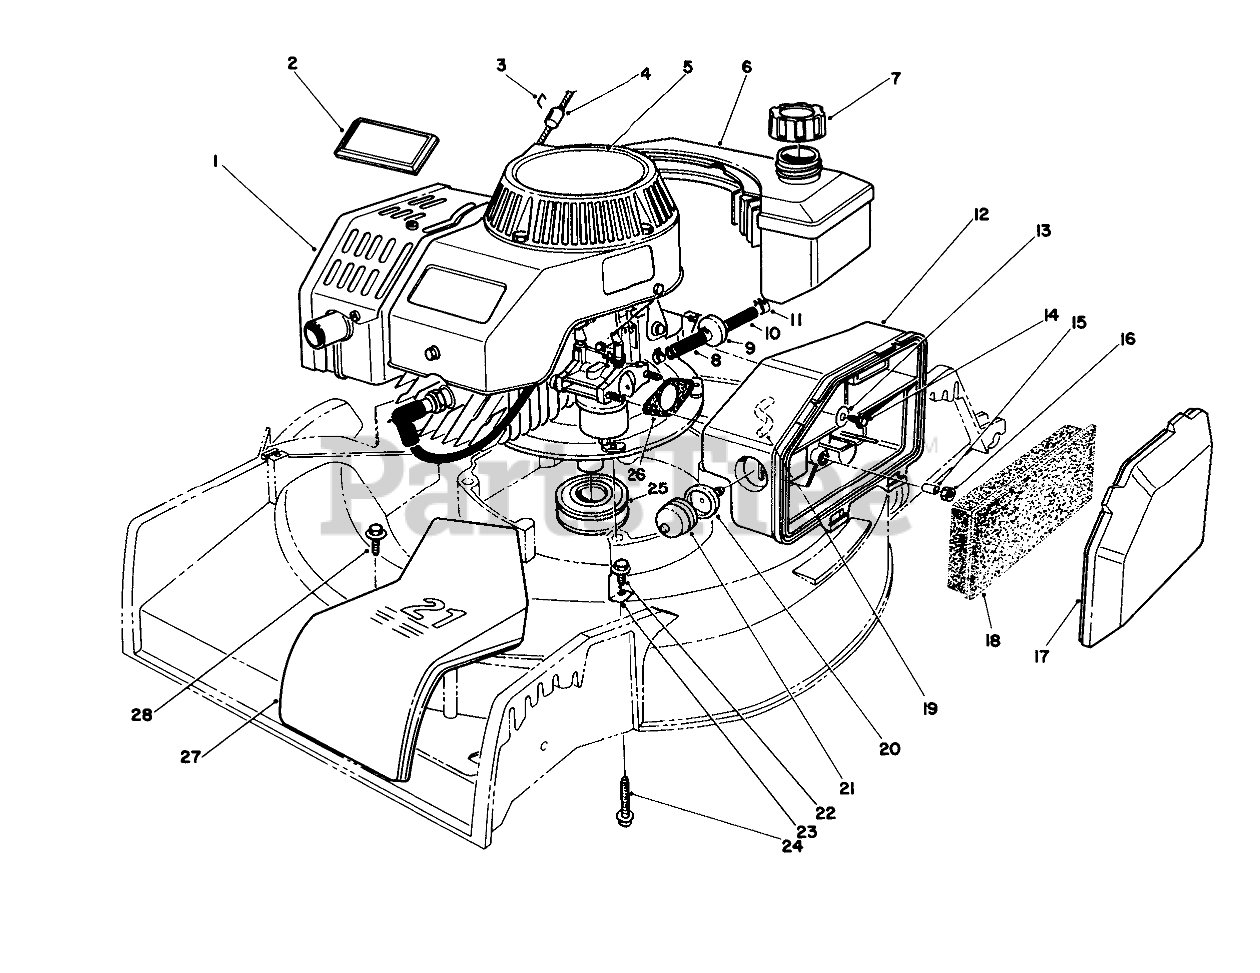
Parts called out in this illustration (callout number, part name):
1	Engine
2	TORO LOGO PLT
3	Staple
5	DECAL - 2 CYC RECOIL
6	FUEL TANK ASM
7	GAS CAP ASM
8	HOSE-FUEL
9	FILTER-FUEL
10	HOSE-FUEL
11	CLAMP-FUEL LINE
12	BODY-AIR CLEANER
13	WASHER-FLAT
14	SCREW-HH
15	SPACER
17	COVER-AIR CLEANER
18	ELEMENT-AIR CLEANER
19	HOSE-PRIMER
20	BODY-PRIMER
21	BULB-PRIMER
22	SCREW-HWHTF
23	BELT GUIDE
24	SCREW-HHF, WHIZ
25	PULLEY-DRIVER
26	GASKET-AIR CLEANER
27	BELT COVER 21" S D
28	SCREW
